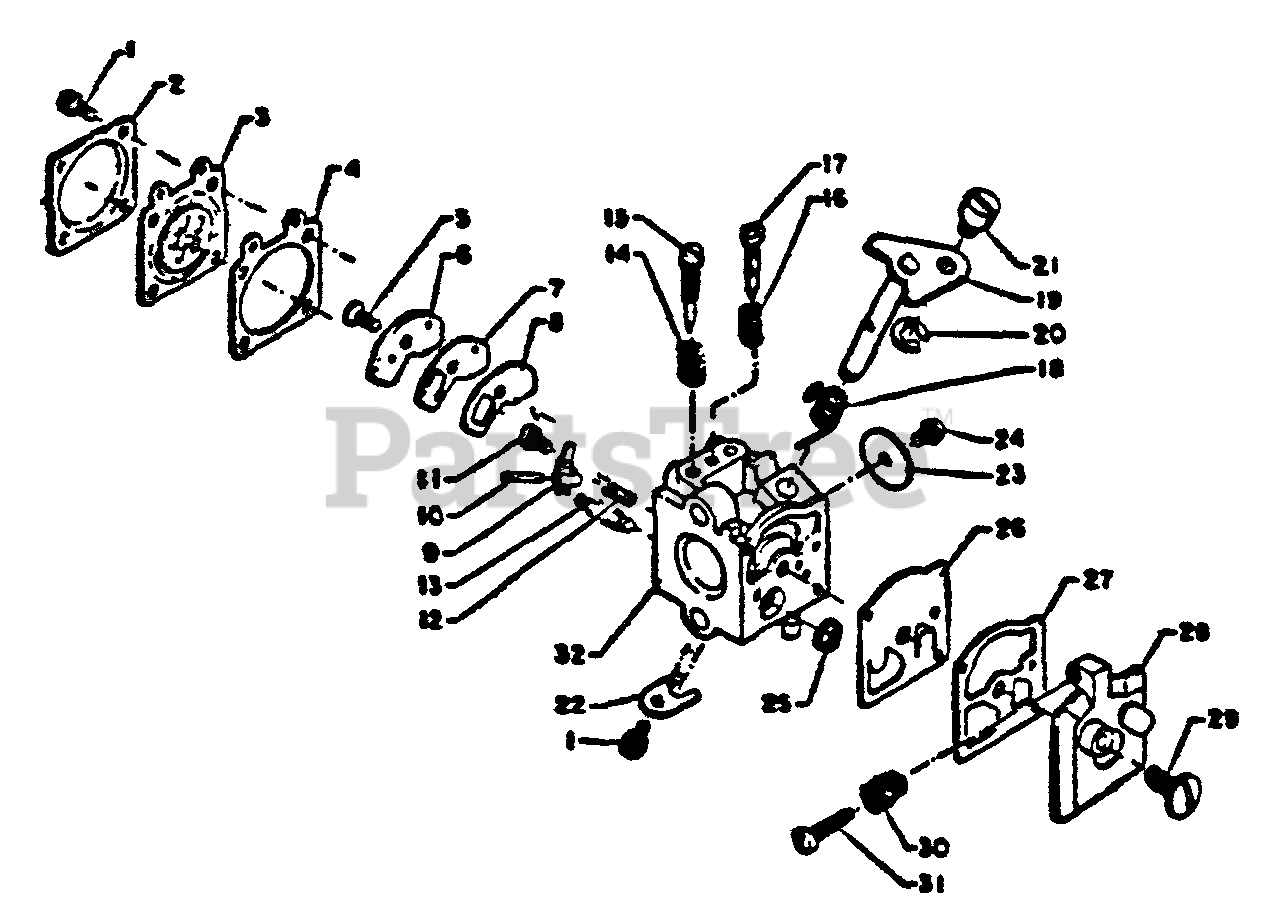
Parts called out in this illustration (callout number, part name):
1	SCREW
2	COVER, METERING DIAPHRAGM
3	DIAPHRAGM, METERING
4	GASKET, METERING
5	SCREW, CIRCUIT PLATE
6	PLATE, CIRCUIT
8	GASKET, CIRCUIT PLATE
9	LEVER, METERING
10	PIN, METERING LEVER
11	SCREW, METERING LEVER PIN
12	SPRING, METERING LEVER
15	NEEDLE, HIGH SPEED
16	SPRING, IDLE ADJUST
17	NEEDLE, IDLE
18	SPRING, THROTTLE RETURN
19	SHAFT, THROTTLE
20	RING, RETAINING
22	CLIP, THROTTLE SHAFT
23	VALVE, THROTTLE
25	STRAINER
28	COVER, PUMP
30	SPRING, IDLE ADJUST
31	SCREW, IDLE ADJUST
32	BODY, CARBURETOR
